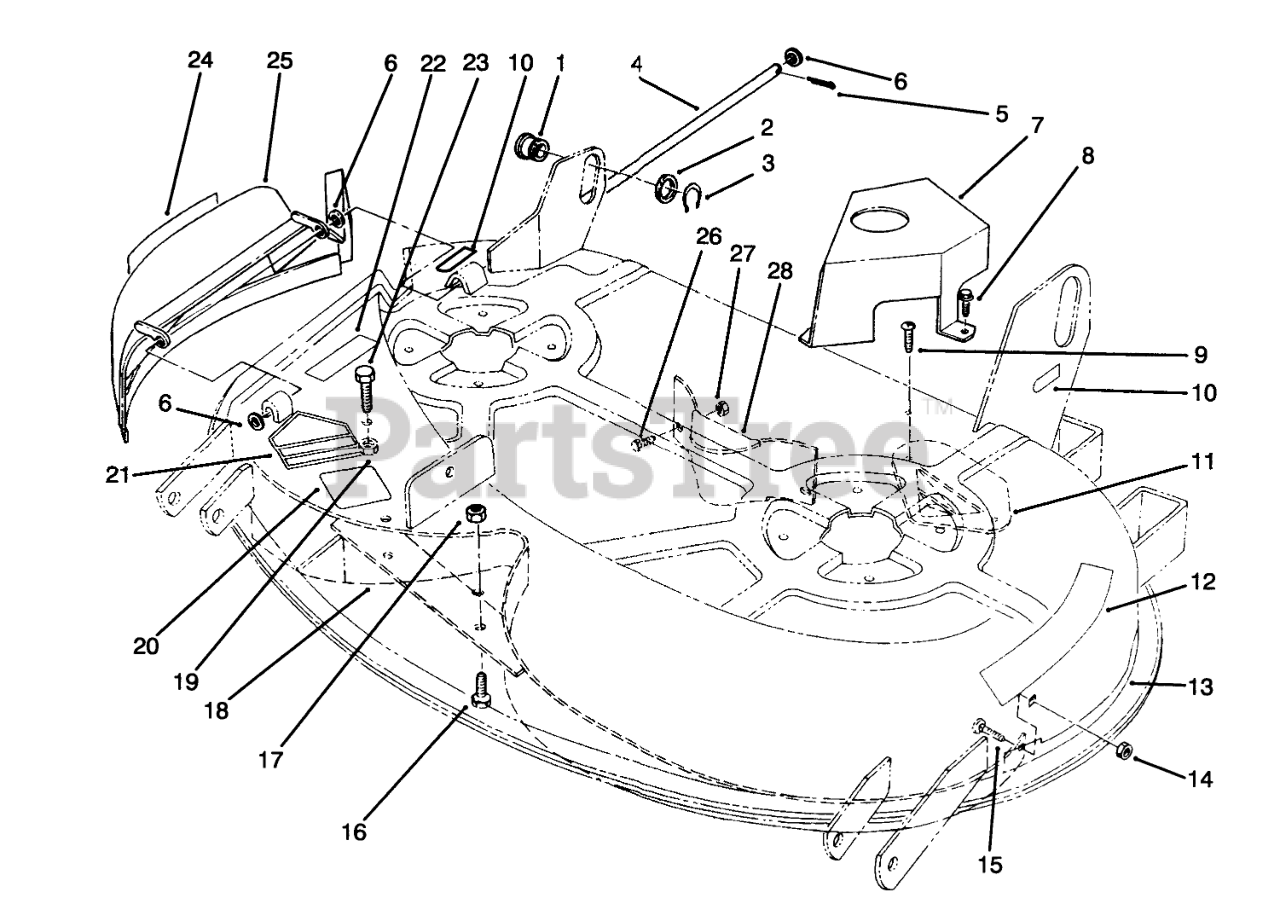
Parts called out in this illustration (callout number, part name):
1	ROLLER-LIFT
2	WASHER
3	RING-RETAINING
5	PIN-COTTER
6	WASHER-PLAIN
7	Cover-Belt
8	SCREW-HWHTF
9	#8 X .625" PHILPS PAN H
10	Decal-Attach-A-Matic
11	PLATE-KICKER
12	DECAL-DANGER
13	DECAL-38" RECYCLER
14	NUT-LOCK, NI
15	BOLT-CARR
16	SCREW-HH
17	NUT-LOCK, NI
18	Baffle-38"
19	NUT-LOCK, NI
20	Decal-Routing
21	DECAL-DANGER
22	DECAL-DANGER
23	SCREW-HH
24	DECAL-DANGER, THROWN OBJECT
25	38 RECYLE PLUG / DECAL
26	SCREW-HH
27	NUT-LOCK, NI
28	Baffle-Rear
